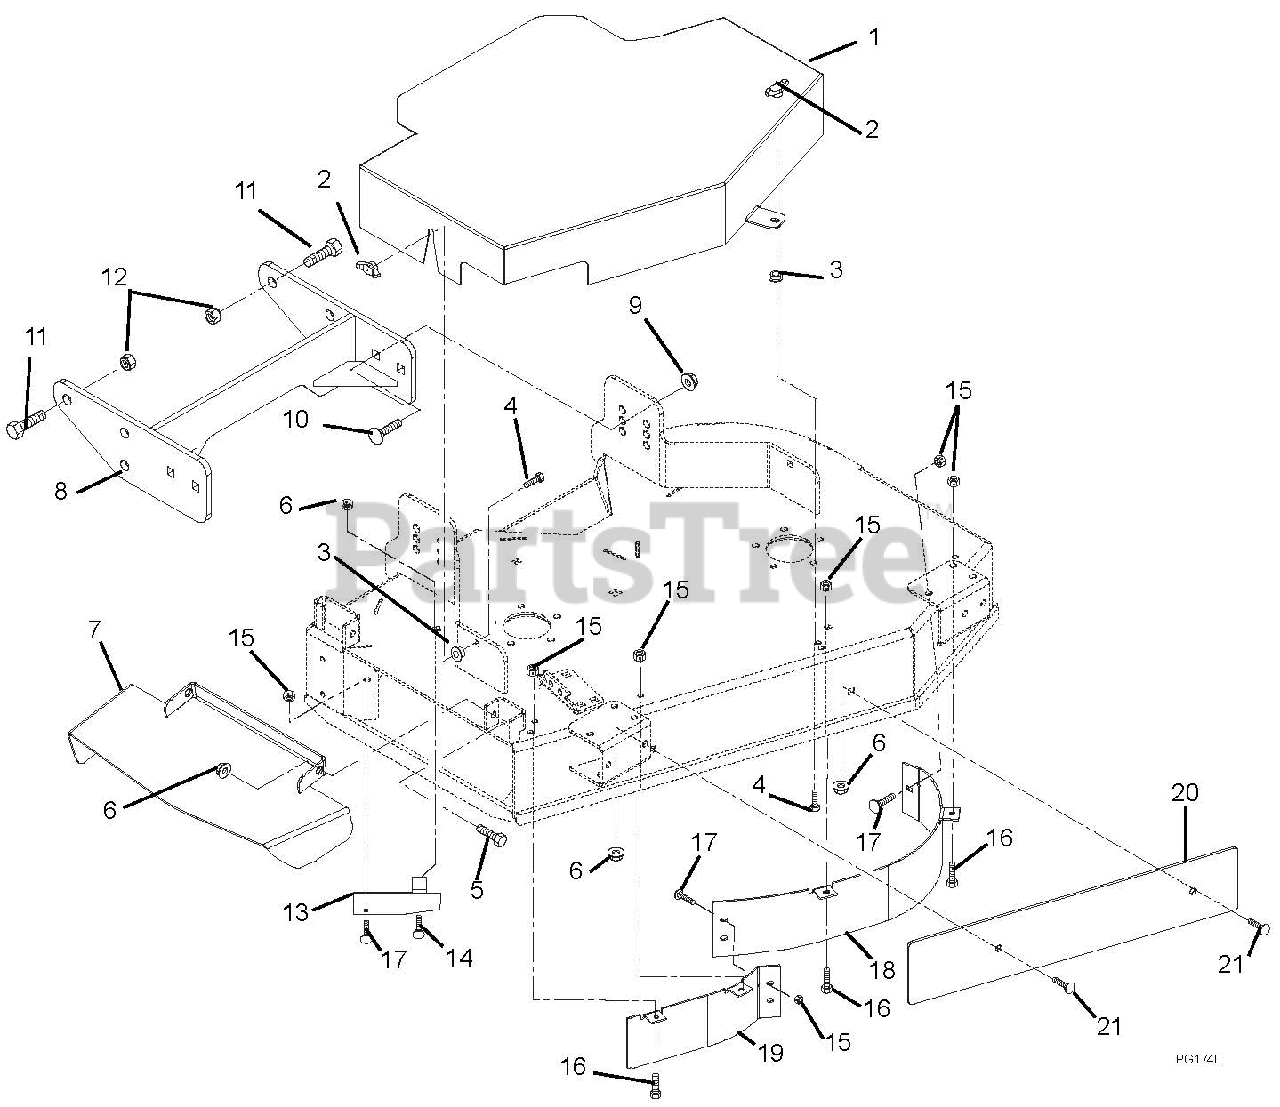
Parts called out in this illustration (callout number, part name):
1	Weldment, Belt Cover 34"
2	Knob, Wing .312-18
3	Nut, Push .312
4	Bolt, Round Head Square Neck .31-18 x 1.0
5	Bolt, Shoulder .38-16 x .50
6	Nut, Locking Top Flange .38-16
7	Weldment, 34" Discharge Chute
8	Weldment, Mower Mounting
9	Nut, Locking Top Flange .50-13
10	Bolt, Round Head Square Neck .50-13 x 1.25
11	Bolt, Hex .62-11 x 1.50
12	Nut, Locking Nylon .625-11
13	Baffle, Deflector
14	Bolt-Round Head Square Neck .38-16 x 1.00 Grade 5
15	Nut-Locking-Top-Flange .31-18
16	Bolt-Hex .31-18 x .75 Grade 5
17	Bolt-Round Head Square Neck .31-18 x .75 Grade 5
18	Baffle, 34" Front Left Hand
19	Baffle, 34" Front Right Hand
20	Weight, Pro Steer
21	Bolt, Round Head Square Neck .38-16 x 1.25
